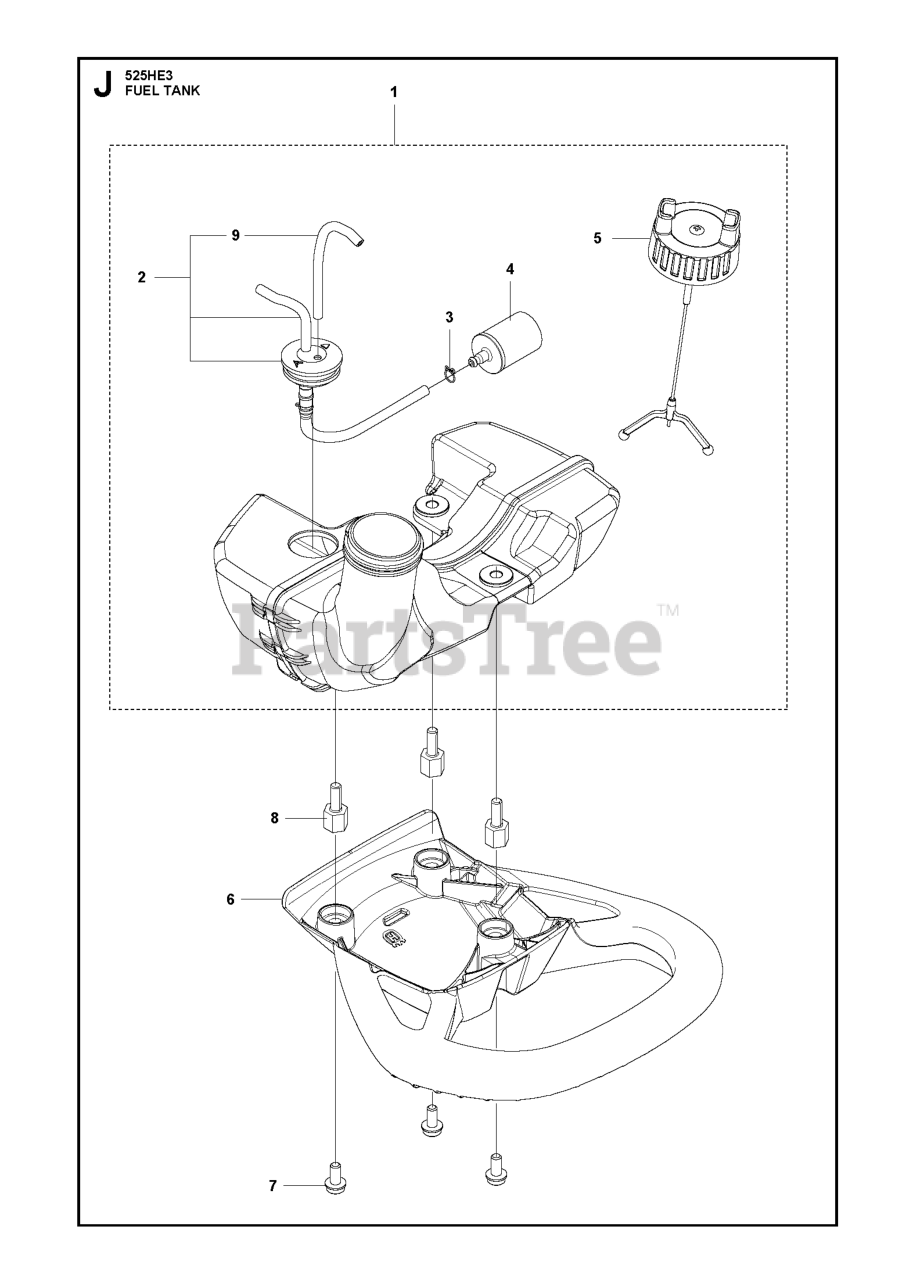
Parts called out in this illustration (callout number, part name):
1	FUEL TANK ASSY
2	Fuel Hoses
4	RP FUEL FILTER
6	BUMPER ASSY
7	SCREW ITXSCM
8	STUD SCREW M5XM5
